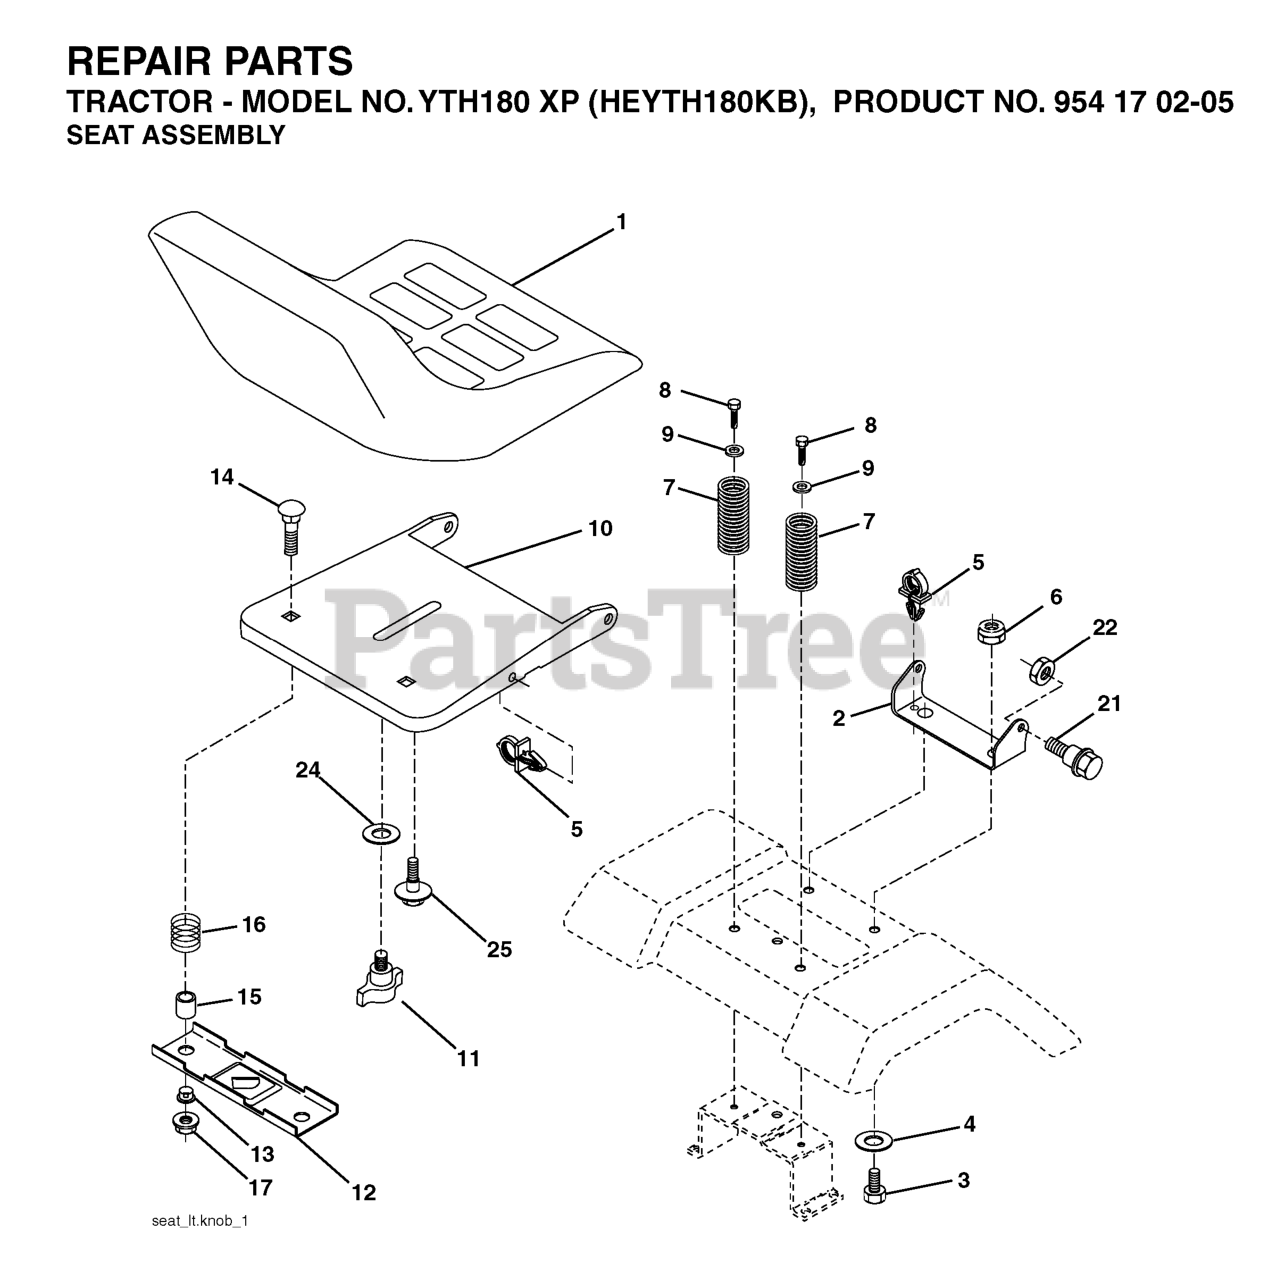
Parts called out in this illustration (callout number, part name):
1	SEAT
2	SEAT PIVOT BRKT
3	BOLT, HEX 3/8-16X1
6	NUT
7	SPRING COMPRESSION
8	SCREW 3/8-16X1
9	WASHER
10	PAN SEAT
11	KNOB.SEAT.ADJ.WINGNUT
12	BRKT SWITCH
14	BOLT.ROUND.HEAD.SQUARE.NECK
15	SPACER SPLIT
16	SPRING COMPRESSED
17	NUT T
21	BOLT.SHOULDER.5/16-18
22	NUT.71038.31-18.HEX.NYLOCK
25	BOLT,SHOULD
